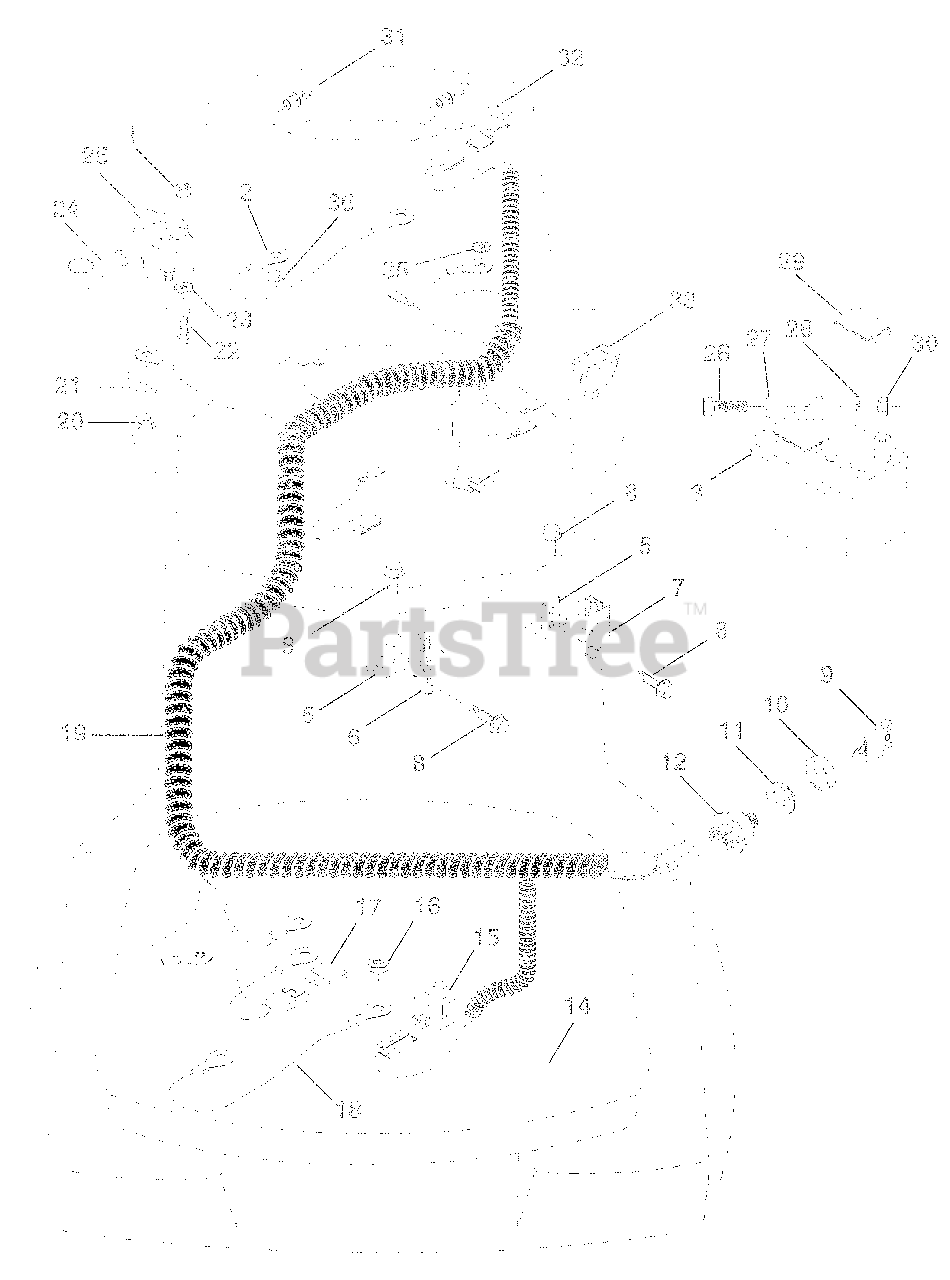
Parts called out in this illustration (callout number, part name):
1	Nut, Hex Keps 1/4-20
2	Assembly, Cable
3	Battery
5	Bracket, Switch
6	Switch, Interlock
7	Switch, interlock
8	Screw, Hex Hd. Tap #10-24 x 1/2
9	Key, Molded
10	Cover, Key ignition
11	Nut, ignition
12	Switch, ignition
14	Tie, Cable
15	Switch, Plunger
16	Nut, Hex, Keps 5/16-18
18	Assembly, Cable
19	Harness, Ignition
20	Nut, Hex Jam 1/4-20
21	Washer, Lock 1/4
22	Bolt, Fin. Hex 1/4-20 UNC x 1/2 Gr. 5
23	Washer, Lock Ext. Tooth 1/4
24	Cover, Terminal
25	Solenoid
26	Bolt, Hex Hd. 1/4-20 UNC x 3/4
27	Washer 9/32 x 5/8 x 16
28	Washer, Lock 1/4
29	Cap, Battery
30	Nut, Fin. Hex 1/4-20 UNC
31	Bulb, Light
32	Socket, Light Harness
33	Switch, Light
35	Lockwasher Ext. Tooth 3/8
